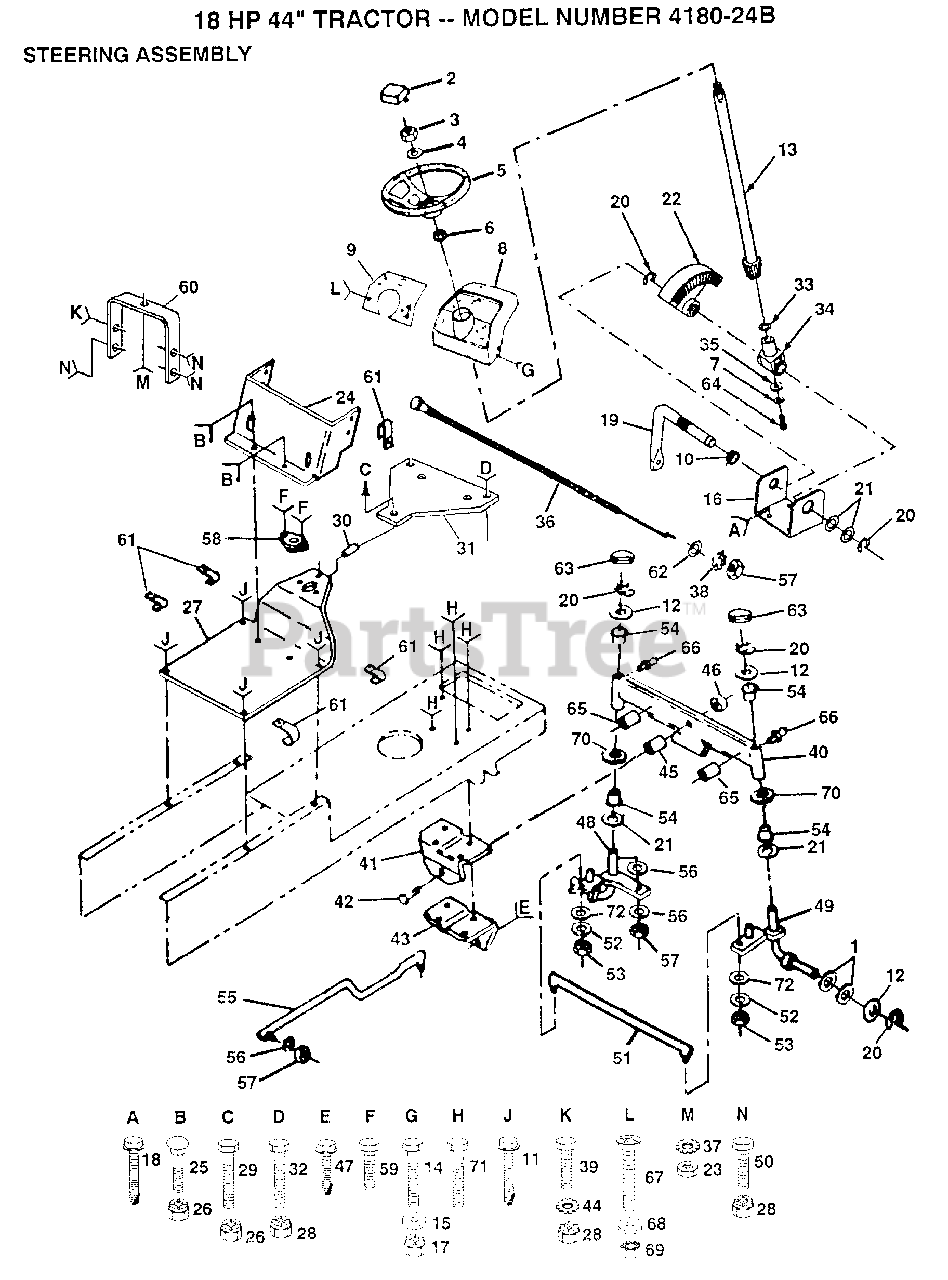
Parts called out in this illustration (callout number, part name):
1	WASHER
2	"INSERT,STR WHEEL"
4	WASHER
6	ADAPTER LT
7	LOCKWASHER
10	NYLINER T
11	SCREW LT
12	WASHER
14	BOLT
15	WASHER
16	"BRKT,STEERING"
18	SCREW
20	RING
21	WASHER .T
24	LOWER DASH
25	SCREW
29	BOLT
30	SPACER
33	THRUST WASHER
34	SUPPORT.SHAFT
36	CHOKE CONTROL
38	LOCKWASHER
39	BOLT
40	FRONT AXLE
41	SUPPORT-SADDL T
42	BOLT LT
43	SUPPORT.SADDLE.FT
44	LOCKWASHER
45	BEARING
47	SCREW LT
48	SPINDLE LH
49	SPINDLE RH
51	TIE ROD
52	LOCKWASHER
53	NUT.LOCK.5/16-24
54	COL. SRTG. BEAR.
56	LOCKWASHER
60	SUPPORT ASS'Y
61	CLIP T
62	WASHER
63	CAP
64	"SCREW,SPECIAL"
65	AXLE PIN
66	ZERK M
67	SCREW
68	WASHER
70	WASHER
71	SCREW SPECIAL
72	WASHER M
